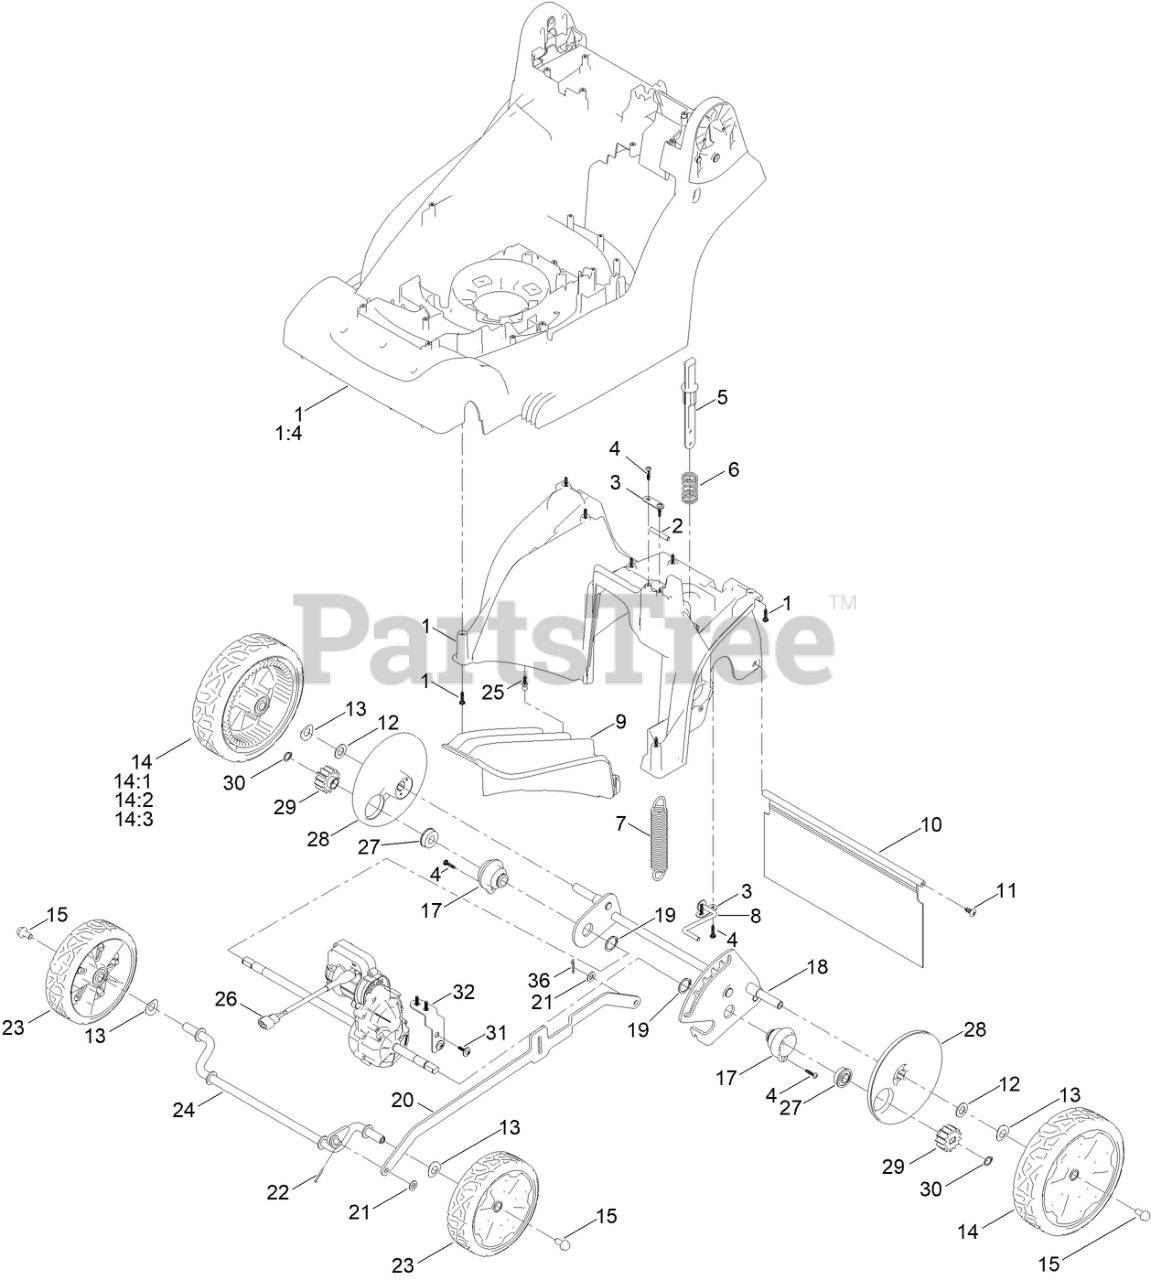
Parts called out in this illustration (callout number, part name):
1	DECK, GLUED (43)
1:4	DECAL - SAFETY
2	BAR, SPRING MOUNT
3	AXLE PLATE, SMALL
5	HOC BUTTON PLUNGER
6	SPRING, HOC BUTTON
7	HOC SPRING, 4 WHEEL
8	HOC WIRE ASM
9	MULCH PLUG
10	SHIELD-TRAILING
11	SCREW-PTH
12	WASHER-PLAIN
13	WAVE WASHER, FRONT WHEELS
14	WHEEL-REAR ASSEMBLY
14:1	WHEEL-TORO REAR
14:2	BEARING
14:3	REAR WHEEL TRIM - TORO
15	BOLT, M8 X 1.25, 16MM
17	BEARING MOUNT
18	REAR AXLE FRAME, ASSY, WHEEL
19	CIRCLIP, EXT
20	Cover, Exhaust-Right
21	WASHER-PLAIN
22	COTTER PIN
23	WHEEL-TORO FRONT ASSEMBLY
24	FRONT AXLE, ASSEMBLY
25	PIN, RETAINING, MULCH PLUG
26	TRANSMISSION, 4-WHEEL
27	BEARING-BALL
28	INNER COVER, REAR WHEEL
29	GEAR-PINION, 13T
30	RING-RETAINING
31	SCREW, T20 X 18, FLANGED
32	BRACKET, GEARBOX, 4-WHEEL
36	COTTER PIN
